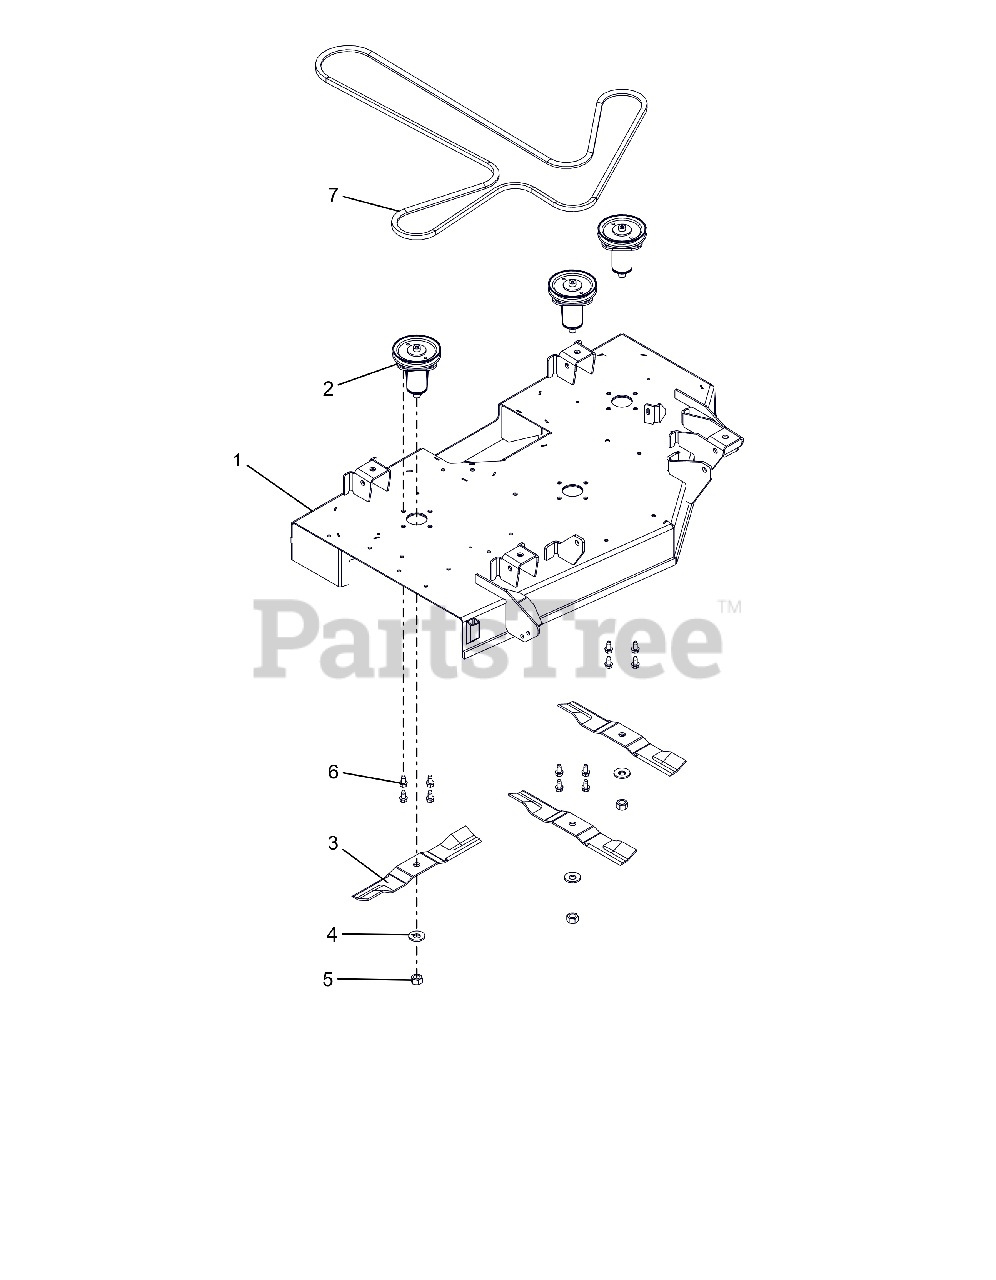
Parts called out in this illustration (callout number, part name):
1	KIT, 42" ARIENS DECK W/DECALS
2	KIT, DECK SPINDLE ASM-IKON-ZTX
3	BLADE, MOWER 15.00"
4	WSHR-BLVL .669X1.535X.138
5	NUT-STD .625-18 ZCC
6	SCR,TAP .375-16X.75 HWH TR ZCC
7	V-BELT, 4L-WRAPPED
